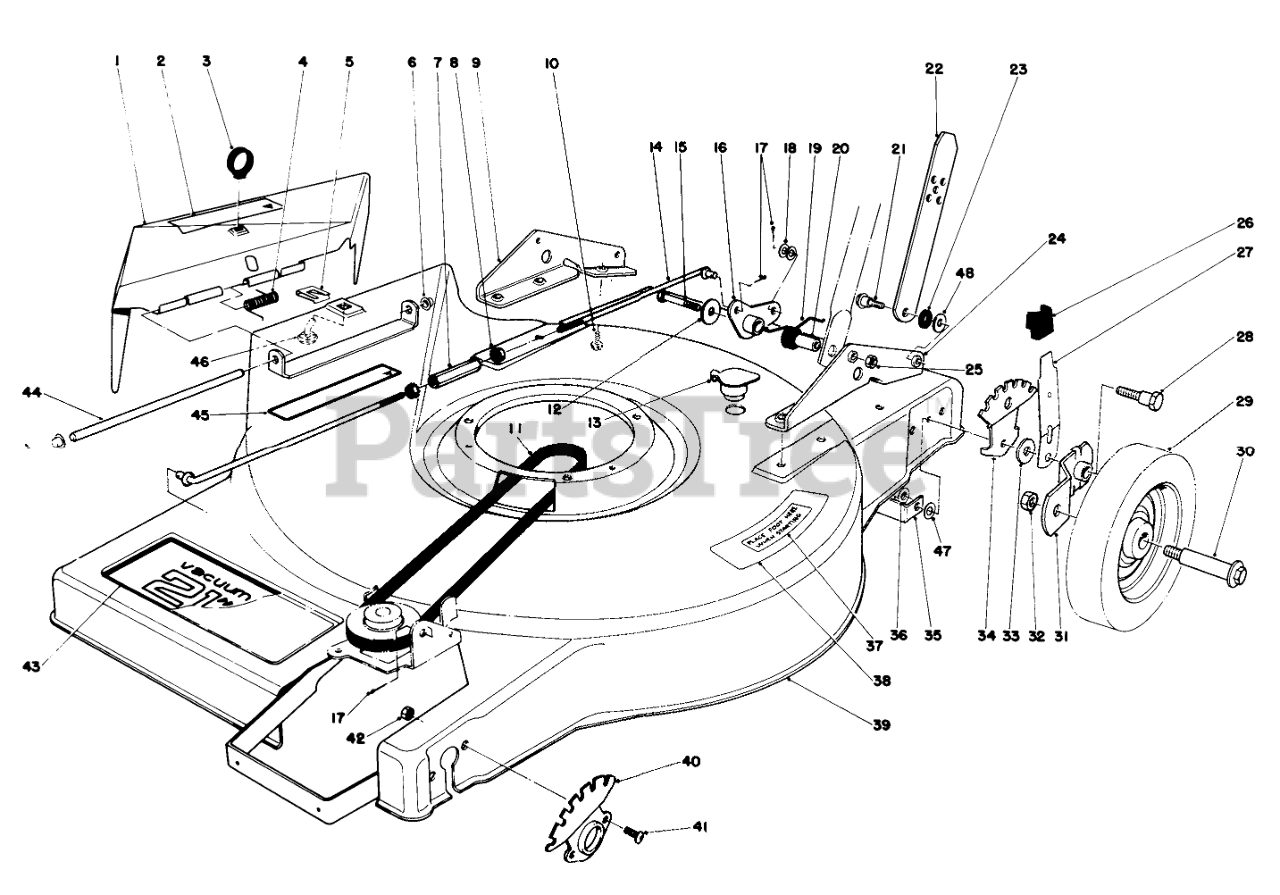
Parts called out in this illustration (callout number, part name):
1	DefIector
2	Decal-Deflector Cover
3	LIFT LOOP
4	TORSION SPRING
5	BAG CHUTE CLIP PIN
6	PUSHNUT-CAP, WASHER
7	CONTROL ROD SLEEVE
8	NUT-KEPS
9	Bracket Handle R.H.
10	SCREW-HWHTF
11	V-BELT
12	WASHER-FLAT
13	WASHOUT PLUG
14	Link Control Rod
15	SCREW-HH
16	Bell Crank
17	PIN-COTTER
18	WASHER-FLAT
19	TORSION SPRING
20	Spacer
21	SCREW-SHOULDER
22	Handle Latch
23	SPACER
24	Bracket-L.H.
25	NUT-LOCK
26	KNOB-ARM
27	SPRING ARM ASM
28	PIVOT SCREW
29	Wheel Assembly
31	PIVOT ARM ASM A
32	Nut
33	PIVOT WASHER
34	Quadrant
35	DECK SUPPORT
37	Decal Step Pad
38	PAD STEP
39	Housing
40	QUADRANT S.P.
41	Capscrew-Button Hd.
42	NUT-LOCK, CONE
43	Decal Deck
44	DEFLECTOR PIVOT ROD
45	Decal Warning
46	BAG CHUTE PIN
47	WASHER
48	WASHER-PLAIN
